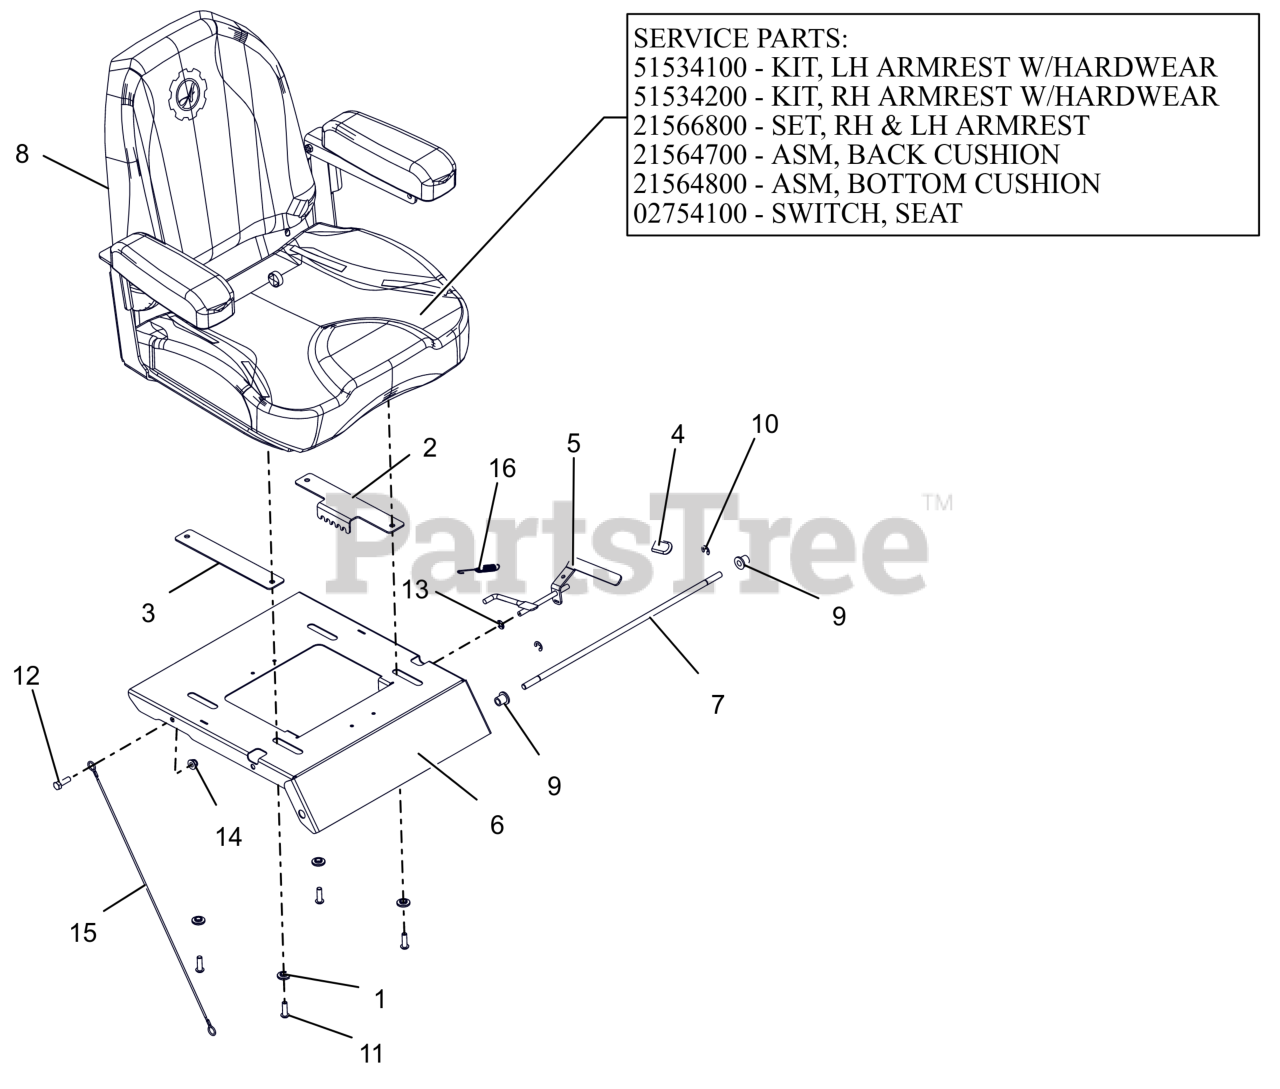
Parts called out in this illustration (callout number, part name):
1	BSHG, FLG .312X.499X.23X.88
2	PLATE, ADJUSTABLE SEAT TRACK
3	PLATE, ADJUSTABLE SEAT SLIDE
4	GRIP, SEAT LEVER, GREY
5	WLDMT, ADJUSTABLE SEAT LATCH
6	PLATE, SEAT
7	ROD, SEAT PIVOT
8	SEAT, IKON XL
8	KIT, ARMREST LH W/HDWR
8	KIT, ARMREST RH W/HDWR
8	SET, LH & RH ARMREST
8	ASM, BACK CUSHION-ARIENS X
8	ASM, BOTTOM CUSHION-ARIENS X
8	SWITCH- SNAP MTG N.O.
9	BSHG-FLG .38X.580X.667X.750
10	RG-RTNG-EXT .375X.035 TYP E
11	BLT,SHCS-BTN .31-18X1.00 ZCC
12	BLT,HEX .31-18X1.00 G5 ZCC
13	NUT-PUSH .312
14	NUT,LK-NYL-FLG .31-18 G5ZC120
15	LANYARD, SEAT CABLE .093X19.5
16	SG-TENS .043X.44X3.31 WLD 5.8
